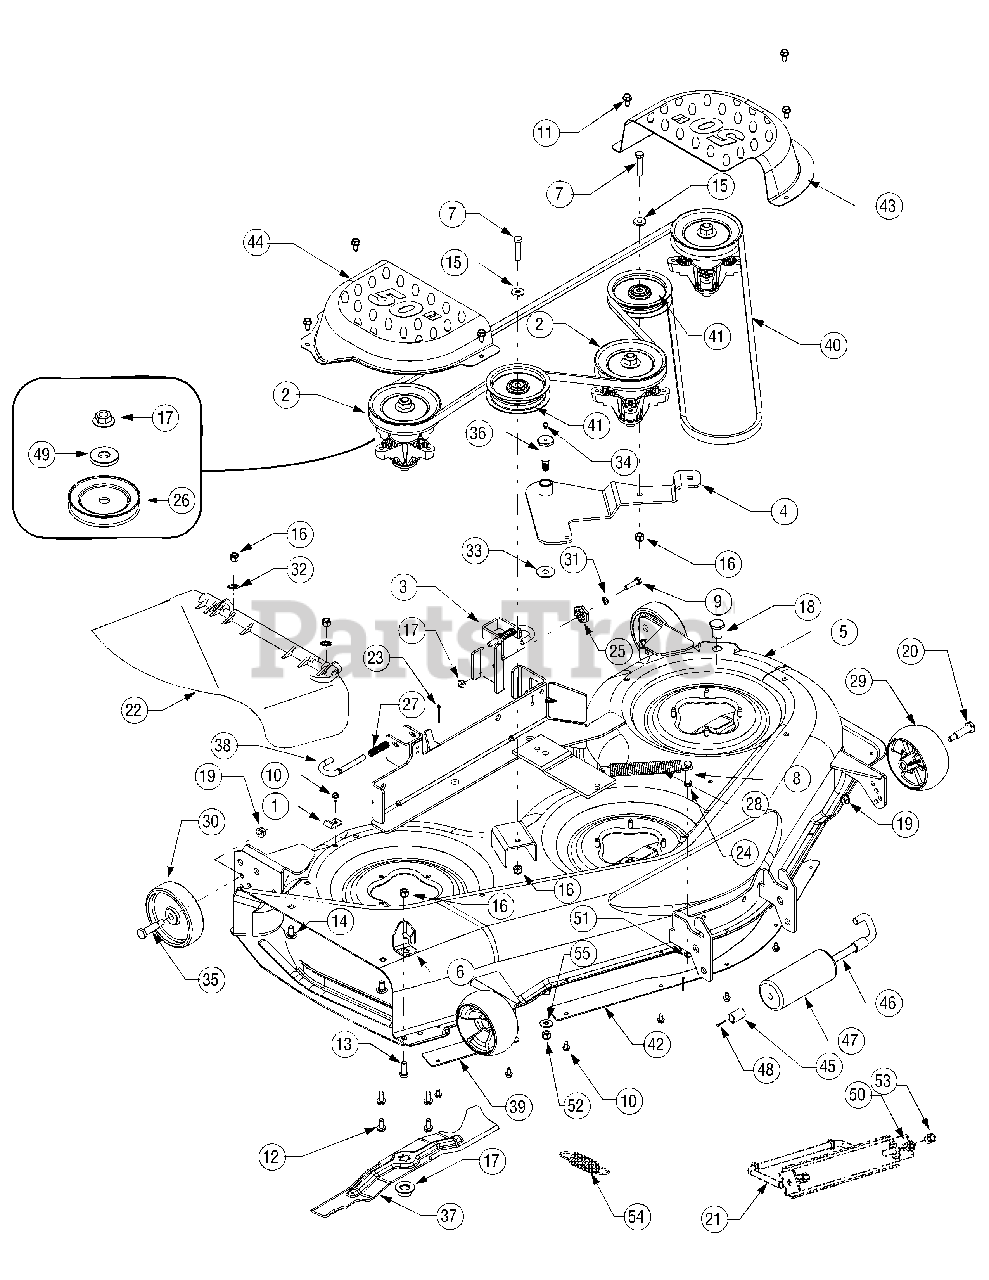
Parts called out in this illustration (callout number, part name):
1	Hook, Retainer
2	Spindle Assembly
7	Screw, 3/8-16, 1.75
8	Screw, 5/16-18 x 2.00
9	Screw, 5/16-18, 1.25, Gr5
10	Screw, 1/4-20 x 0.5
11	Screw, 5/16-18 x.500
12	Screw, 5/16-18 x.75
13	Screw, 3/8-16 x 1.0
14	Screw, Carriage, 3/8-16 x.75
15	Washer, Flat,.406 x.875 x.059
16	Nut, Nylon Lock, 3/8-16
17	Nut, Hex, Flange, 5/8-18
18	Plug, Screw, M16 x 1.5
19	Nut, Flange Lock, 3/8-16
20	Shld, Screw, 1/2 Dia. x 2.50 Lg.
21	Rod, Deck, Front
22	Chute Assembly, Side Discharge
23	Pin, Cotter, 1/8 x 1.25
24	Nut, Hex, 5/16-18
25	Deck Adjustment Gear
26	Pulley, 5.39"
27	Spring, Compression,.531 x 1.75
28	Spring, Extension,.94 x 6.74
29	Deck Wheel, 5.0
30	Deck Wheel, 5.0
31	Washer, Lock, 5/16
32	Push Nut, 3/8
33	Washer, Flat,.442 x 1.38 x.060
34	Fitting, Lube, 3/16
35	Shoulder Screw
36	Screw, Shoulder,.68 x 1.59
37	Blade, 17.90
38	Rod, Deck Release.375 Dia.
40	Belt, V-Type, Aramid
41	Pulley, Idler, 3.5"
45	Spacer, 1.1"
46	Roller Pin
48	Pin, Cotter, 3/32 x 1.00
49	Wash, Flat,.760 x 1.50 x.120
50	Nut, Hex, 1/2-13
51	Nut, Flange Lock, 5/16-18
52	Nut, Hex, 7/16-14
53	Nut, Hex Lock, 1/2-13
54	Spring, Extension, 1.15 Dia. x 5.99
55	Wash, Bell,.45 x 1.00 x.062
